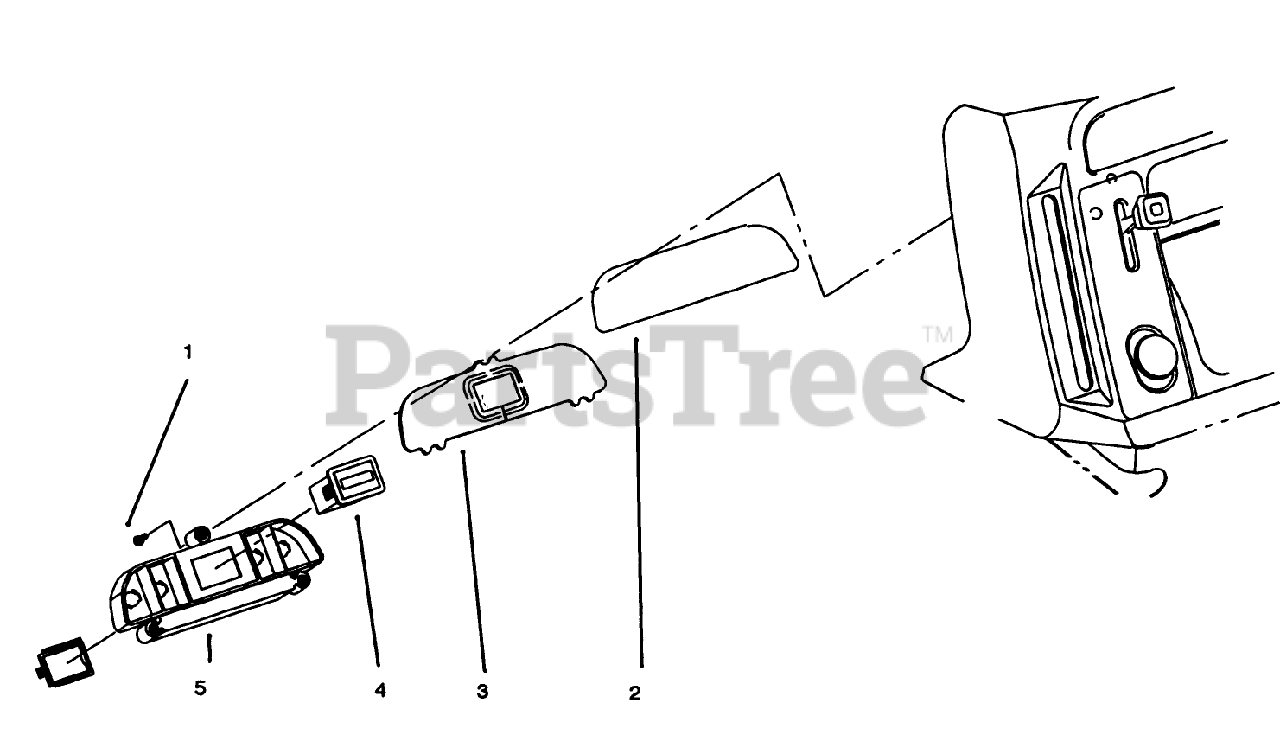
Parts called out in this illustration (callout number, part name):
1	Screw (Ref.)
3	LENS-DASH
4	Hour Meter (Ref.)
